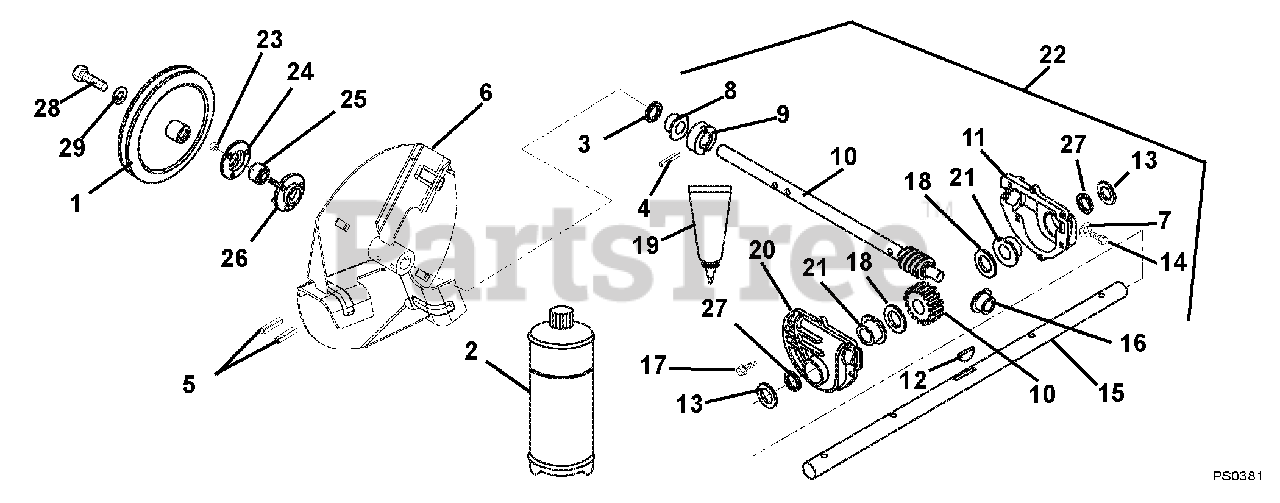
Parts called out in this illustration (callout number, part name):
1	PULLEY, 4L W/HUB, .75 X 8.5
2	ARIENS 16 OZ.BOTTLE OF L2 LUBE
3	SEAL-OIL.748X1.378X.276 RBR OD
4	@PIN-GRV .188X1.25 TP E ALLOY
5	PIN-ROLL .250X1.75
6	WELDMENT, IMPELLER,12" 3 BLADE
7	WSHR-FIBER .437X.656X.032
8	BSHG-FLG .750X1.000X.750X1.250
9	THRUST COLLAR, .75" ID
10	SHAFT AND WORM GEAR ASSEMBLY
11	GEARCASE CASTING, MACHINED LH
12	KEY-WDRF .19X.63 HRD #61
13	@WSHR-FL-STL.812X1.50X.135YWZC
14	SCR-TAP .38-16X.75 ROLOK YZ WX
15	SHAFT, RAKE - 24" (.750 DIA)
15	SHAFT, RAKE - 20" (.750 DIA)
16	BSHG-FLG .502X1X.750
17	@SCR-TAP .25-20X1.00 HWH TR YZ
18	WSHR-FL-STL.755X1.375X.062YWZC
19	LOCTITE 518 GASKET--6ML TUBE
20	GEARCASE CASTING, MACHINED RH
21	BSHG-FLG .753X1.127X.500X1.501
22	GEARCASE, 24" ALUM, SMALL CD
22	GEARCASE, 20" ALUM, SMALL CD
23	@NUT-LK-CTR .25-20 YWZC
24	BEARING FLANGE
25	BRG-BALL .750X1.750X.50
26	BEARING FLANGE
27	SEAL-OIL .750X1.375X.250
28	BLT-HEX .31-24X.75 YWZC GR5
29	WSHR-LK .312X.097 HVY YWZC
